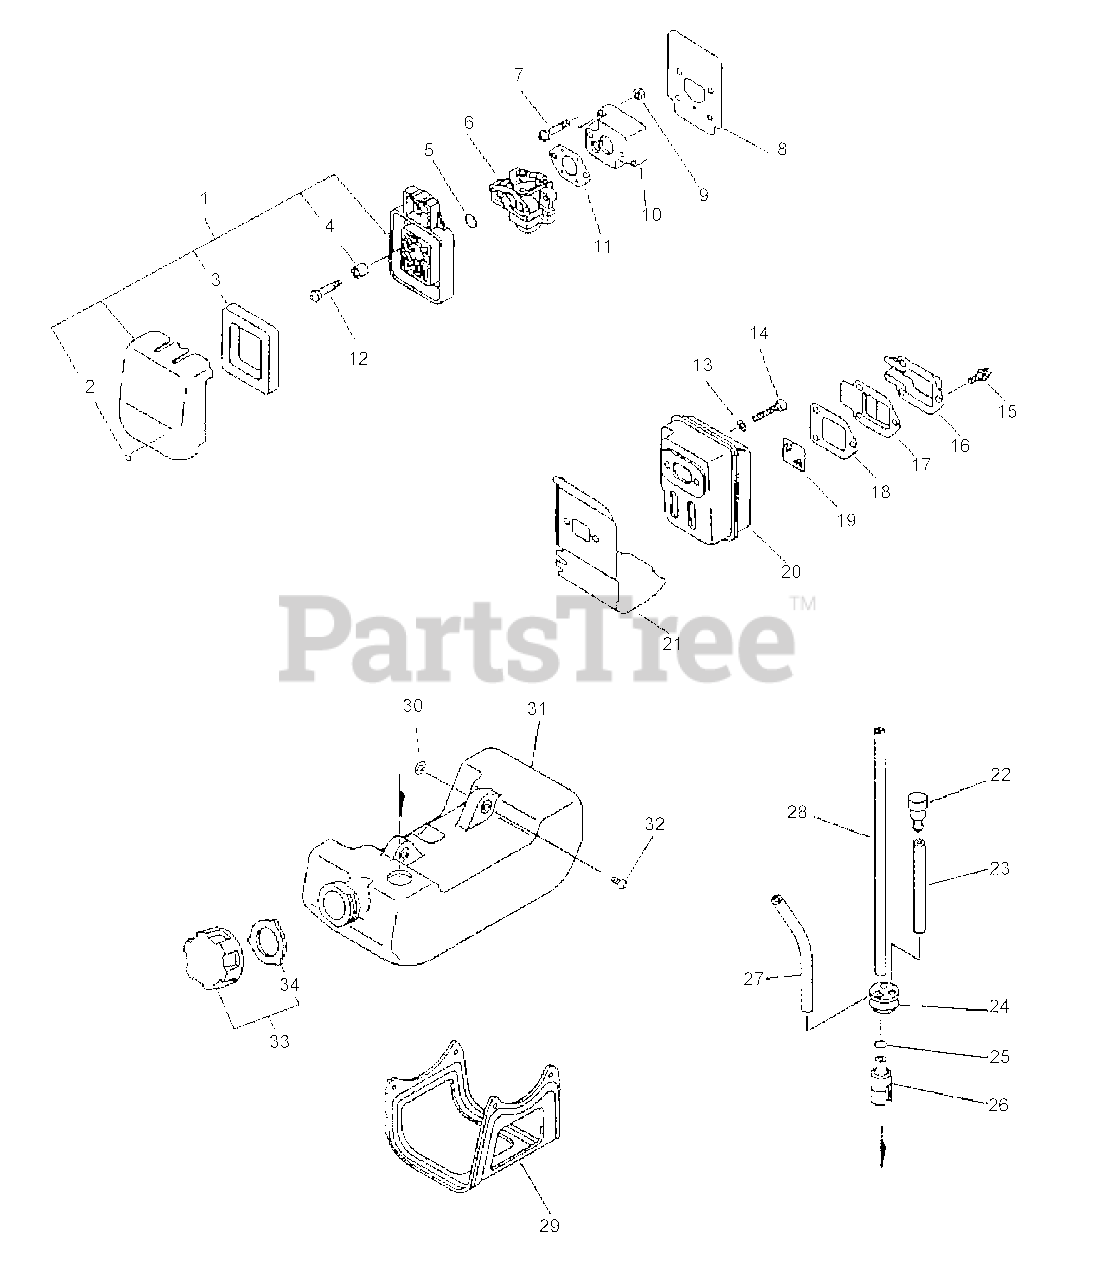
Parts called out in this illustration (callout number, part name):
1	AIR CLEANER ASSY
3	FILTER, AIR
4	SLEEVE
5	O-RING - 15
6	CARBURETOR WYL-53
7	SCREW - 5X20
8	SHIELD, INTAKE
10	INSULATOR, INTAKE
11	GASKET, INTAKE
12	SCREW - 5X64
13	WASHER - 5
14	SCREW - 5X55
15	SCREW - 4X10
16	GUIDE, EXHAUST
16	GUIDE, EXHAUST - OUTER
17	GASKET, EXHAUST - INNER
18	GASKET, EXHAUST
19	SCREEN, SPARK ARRESTOR
20	MUFFLER
21	GASKET, EXHAUST
22	VENT, FUEL TANK
23	PIPE - 3X5X30 -- BLACK
24	GROMMET
25	CLIP - 6
26	FILTER, FUEL
27	PIPE - 3X6X80 -- CLEAR
28	PIPE - 3X5X160 -- BLACK
29	GUARD, FUEL TANK
30	WASHER - 5
31	FUEL TANK ASSY
32	SCREW - 5X16
33	CAP ASSY
34	GASKET, CAP
